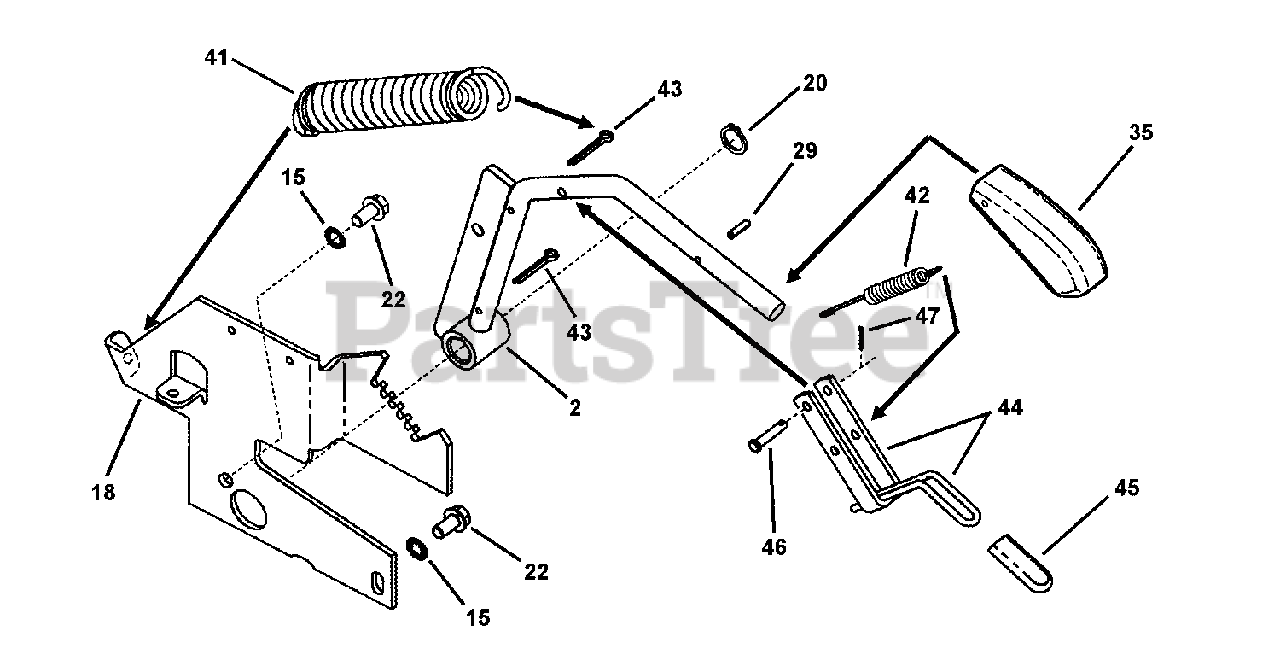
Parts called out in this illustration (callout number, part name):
2	LEVER, Height Adjustment Lift (Weldment)
15	WASHER, 3/8" Internal Tooth Lock
18	QUADRANT, Lift Lever
20	RING, 3/4" Retaining
22	SCREW, 3/8-16 x 3/4" Hex Washer Self-Tap
29	ROLL PIN, 3/16 x 3/4"
35	GRIP, Height Adjustment Lever
41	SPRING Extension
42	SPRING, Latch
43	PIN, 3/16 x 1-1/2" Cotter
44	LATCH Weldment
45	GRIP, Lift Latch
46	PIN, 1/4 x 1-1/4" Clevis
47	COTTER PIN, 1/16 x 3/4"
